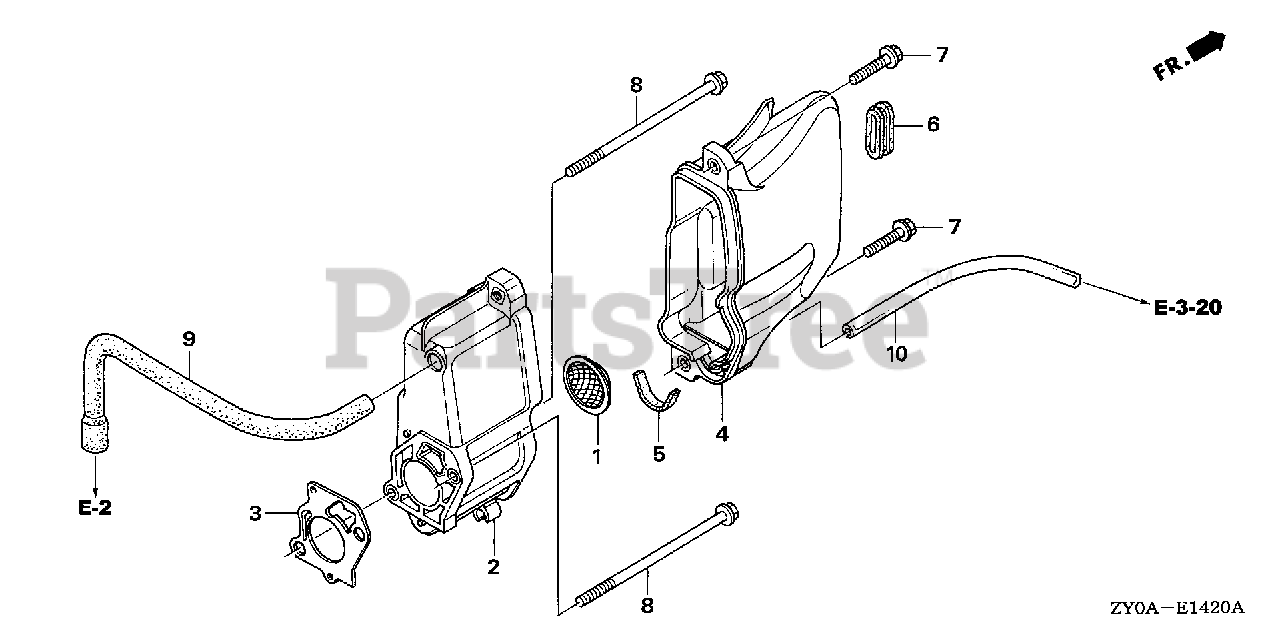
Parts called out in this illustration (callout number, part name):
1	TRAP, FLAME
2	PLATE, MUFFLER
3	GASKET, MUFFLER PLATE
4	COVER, MUFFLER
5	GASKET, MUFFLER COVER
6	RUBBER A, TANK MOUNTING
7	BOLT, FLANGE (6X22)
8	BOLT, FLANGE (6X106)
9	TUBE, BREATHER
10	BULK HOSE, VINYL (4X7X8000) (4X7X120)
